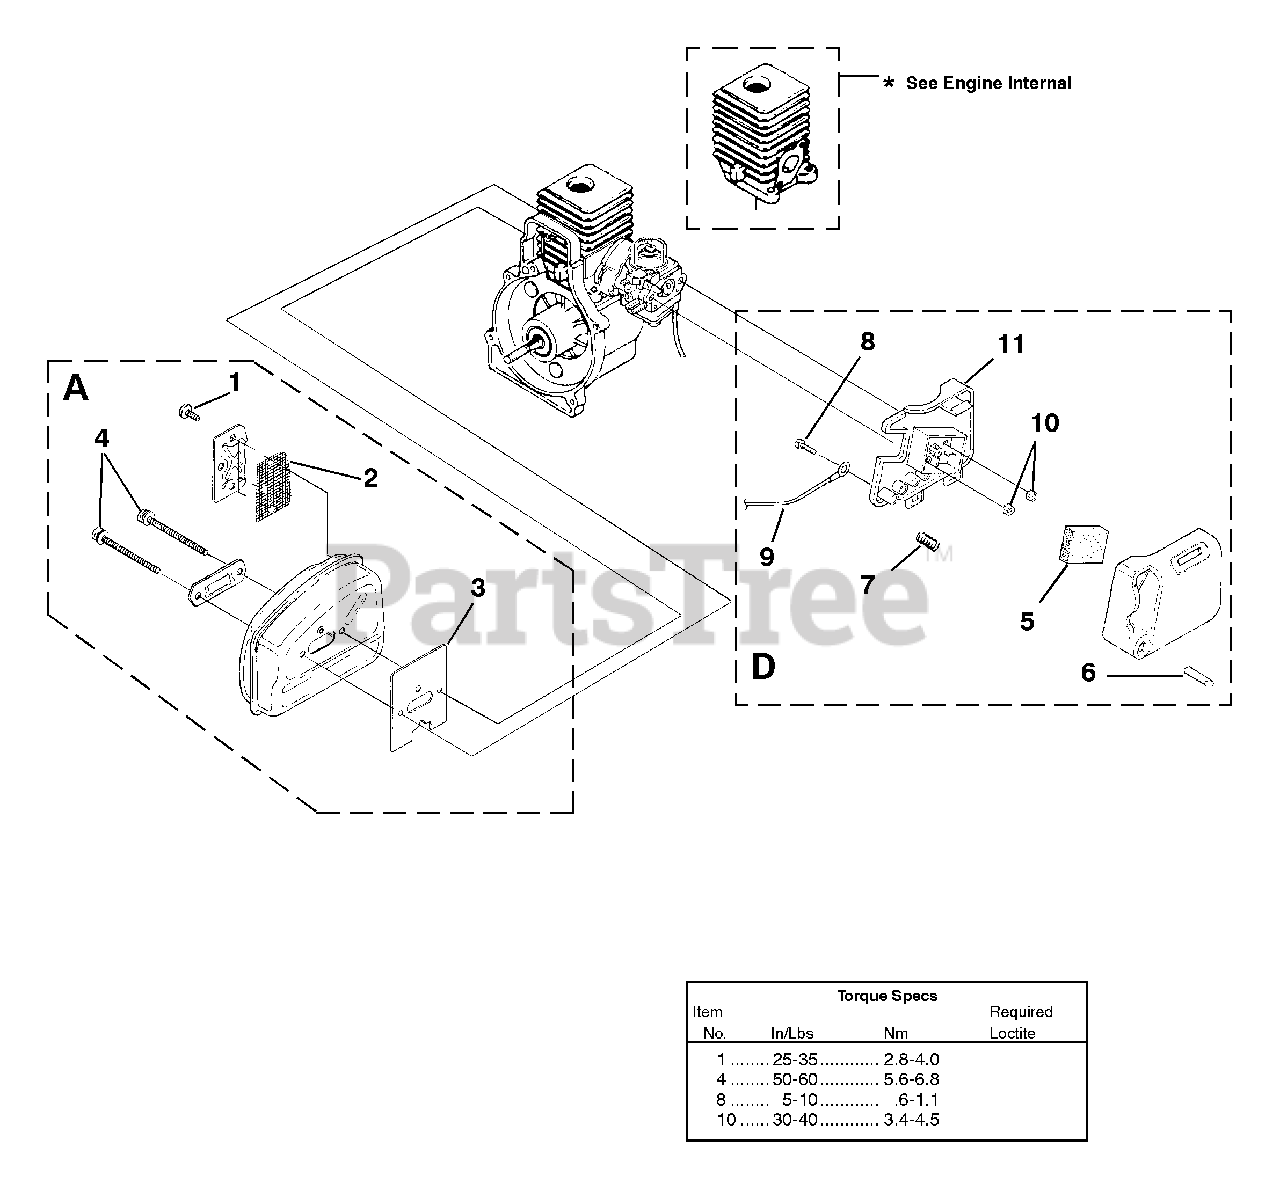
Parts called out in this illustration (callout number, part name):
1	SCREW, Taptite- (8-32 X 3/8")
2	SCREEN-Spark
3	GASKET-Muffler
4	SCREW, Truss Hd. - (10-24 X 2.188)
5	FILTER-Air
6	BUTTON-Switch
7	SPRING-Compression
8	SCREW-Thread Form (6-19 x 1/2")
9	LEAD-Electrical
10	NUT-Hex (10-24)
11	COVER AIR BOX
A	MUFFLER ASSY.
D	AIR FILTER KIT
